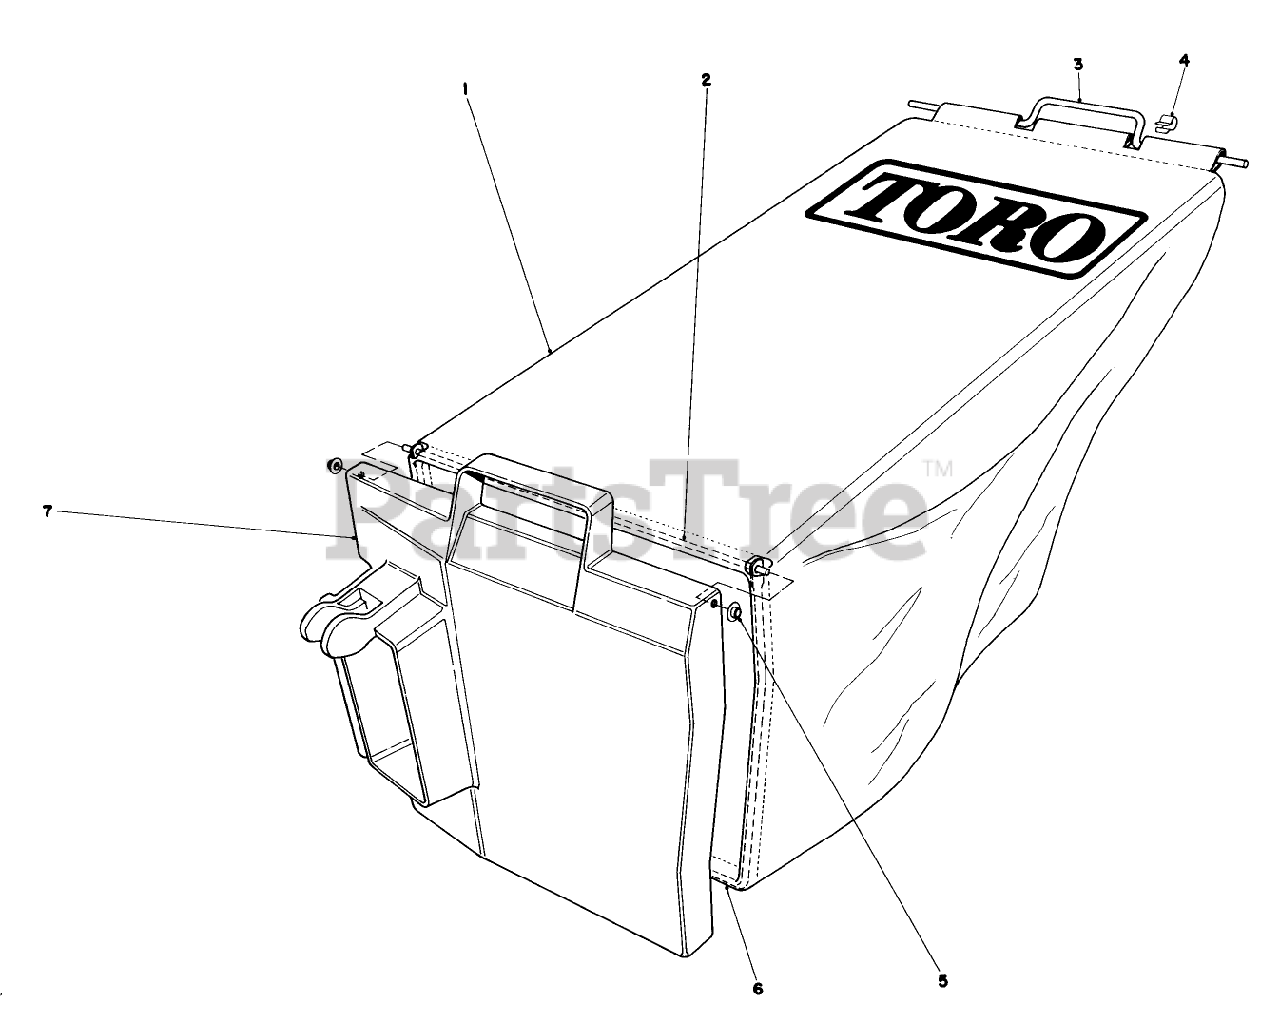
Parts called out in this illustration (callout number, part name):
1	18 BAGGER BAG 33-4552
2	HINGE
3	Handle Bag
5	NUT-PUSH
6	Frame Bag
7	Door-Bag
